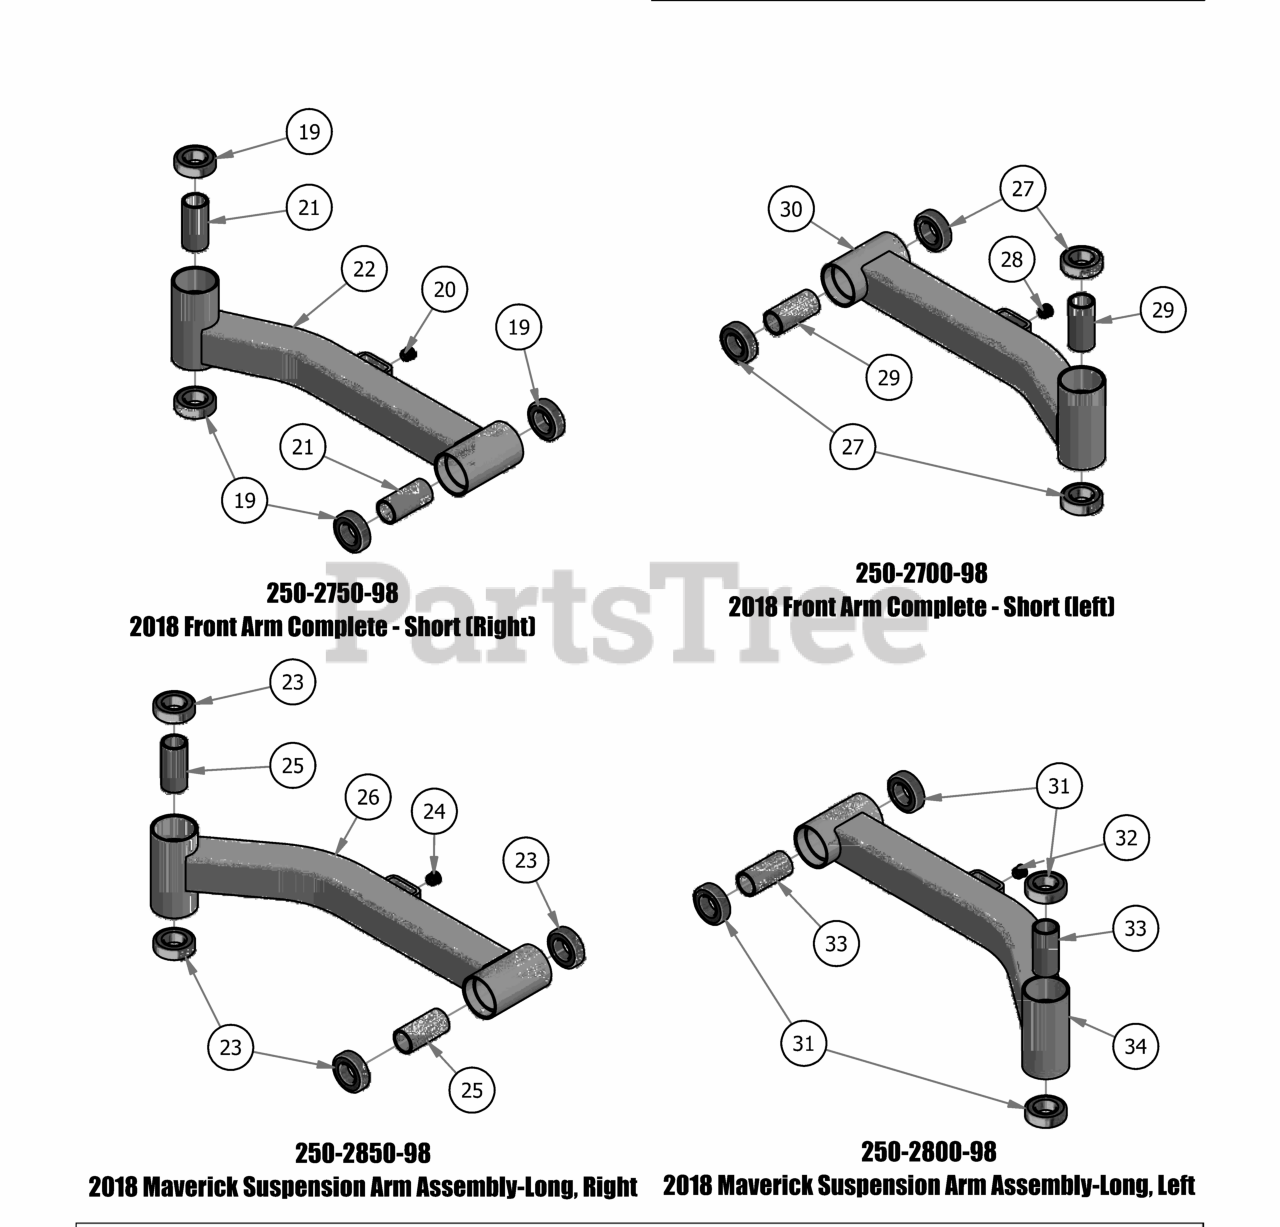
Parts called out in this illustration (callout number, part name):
19	Caster Bearing 2016 - 1641 Bearing
20	5/8 Round Insert
21	2016 Front Bearing Spacer
22	2018 Front Arm - Short (right)
23	Caster Bearing 2016 - 1641 Bearing
24	5/8 Round Insert
25	2016 Front Bearing Spacer
26	2018 Maverick Suspension Arm-Long, Right
27	Caster Bearing 2016 - 1641 Bearing
28	5/8 Round Insert
29	2016 Front Bearing Spacer
30	2018 Front Arm - Short (left)
31	Caster Bearing 2016 - 1641 Bearing
32	5/8 Round Insert
33	2016 Front Bearing Spacer
34	2018 Maverick Suspension Arm Long-Left
